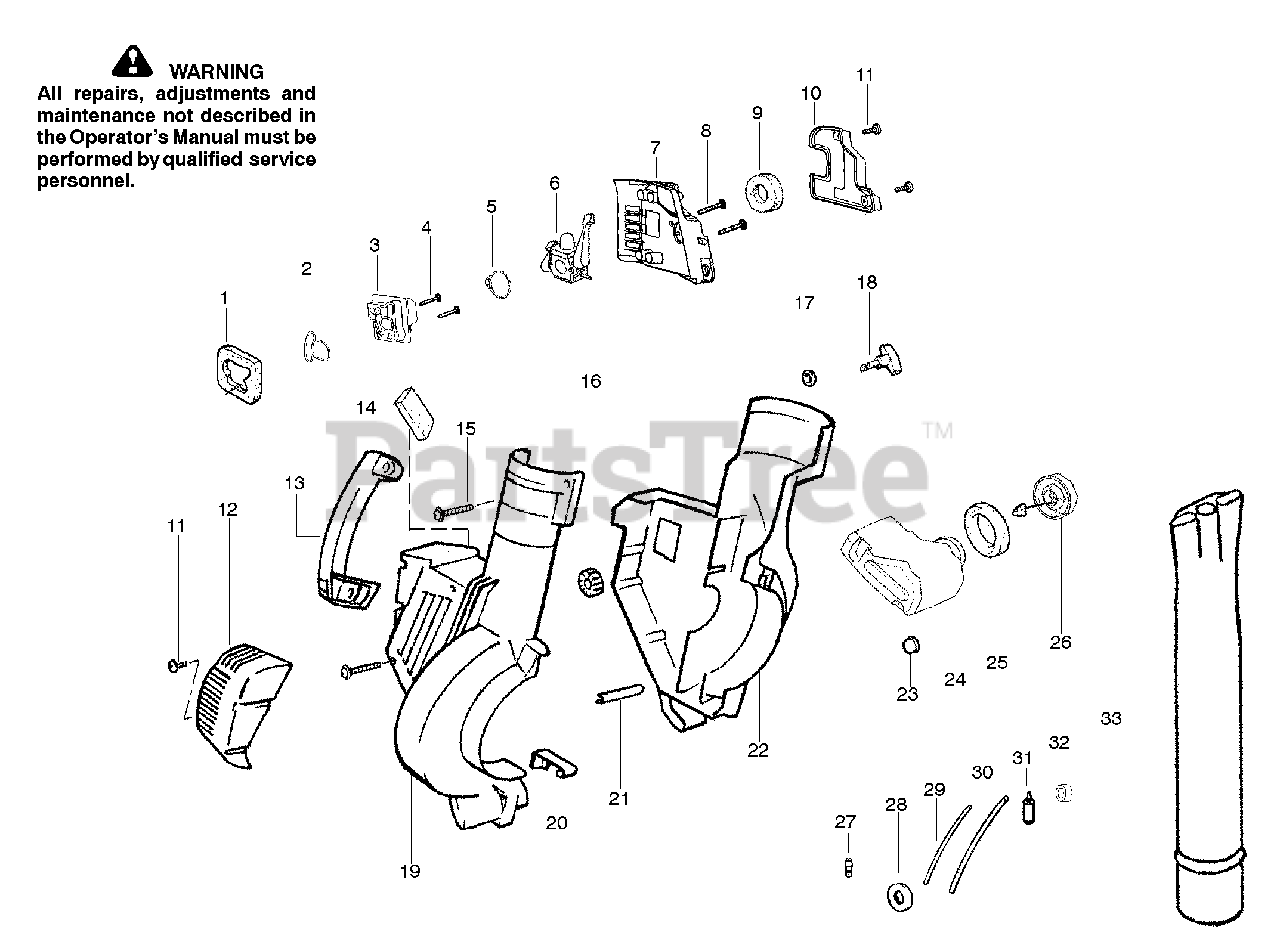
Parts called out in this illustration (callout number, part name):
1	Air Dam (kit)
2	Gasket-Adapter (kit)
3	Carburetor Adaptor
5	Gasket-Carburetor (kit)
6	Kit-Carb Ass'y. Zama-(C1Q-W11C)
6	Kit-Carb Ass'y. Walbro-(WT-606)
8	Screw-Carb.
9	Filter-Air
10	Cover-Air Filter
12	Guard-Muffler
14	Foam - 71.12mm (kit)
16	Isolator
18	Knob-Blower
19	Shroud -RH
20	Spring-Cover Latch
21	Guide-Starter Rope
22	Shroud-LH
23	Isolator-Crankcase
24	Assy-Fuel Tank
25	Gasket-Fuel Tank
26	Fuel Cap w/Retainer
27	Fitting-Fuel Line
28	Grommet-Shroud
29	Kit-Line Carb/Purge
30	Kit-Line Tank/Purge
31	Assy-Fuel Pick-up
32	Grommet-Fuel line (kit)
33	Tube-Blower
